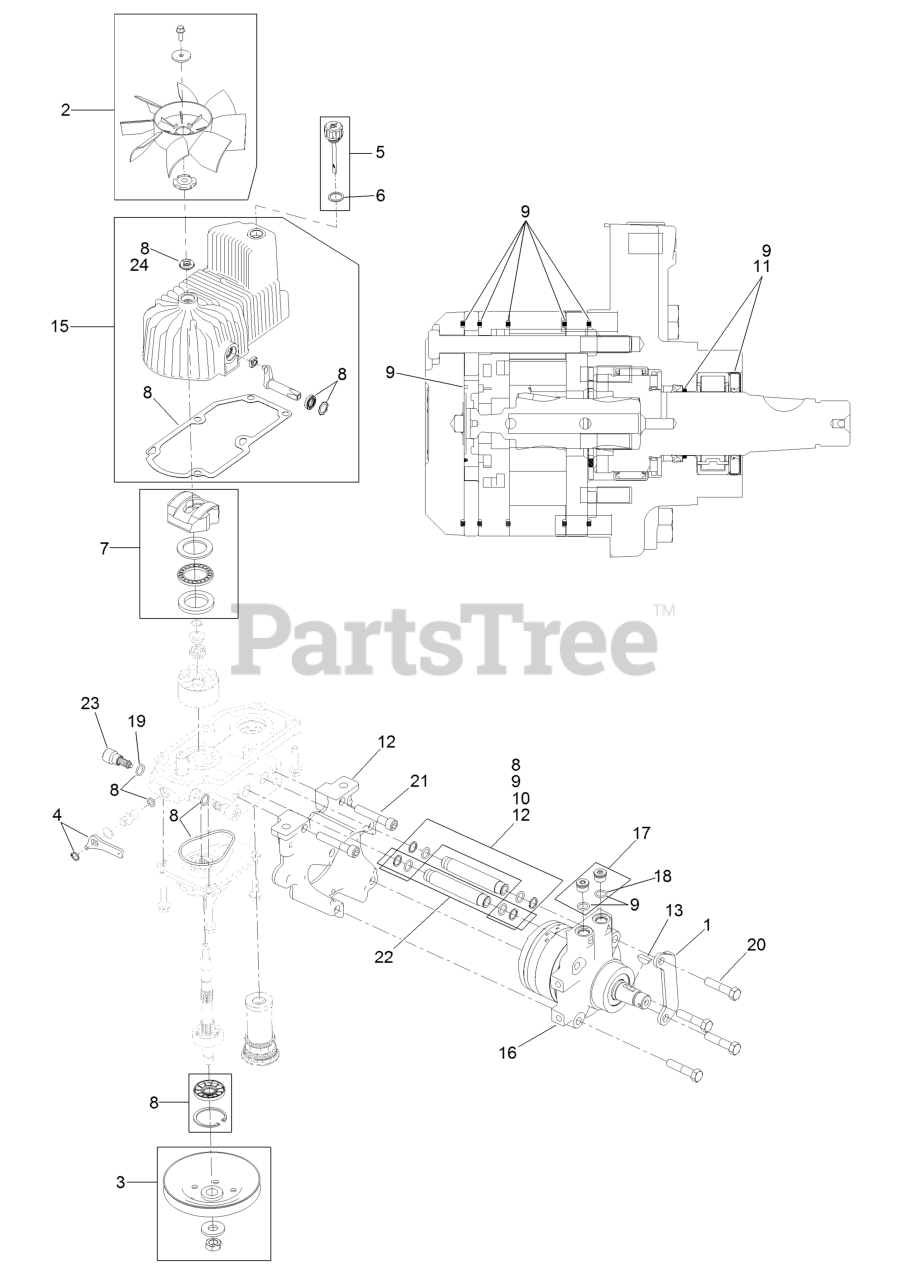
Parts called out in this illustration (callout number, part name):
1	Mount-Shoe, Horse
2	Fan Kit
3	Pulley Kit
4	Handle-Bypass Valve,Hydro
5	Dipstick-Hydro W/Gasket
6	Gasket-Dipstick, Hydro
7	Swash Block Kit
8	Pump Seal Kit
9	Motor Seal Kit
10	Tube Seal Kit
11	Output Shaft Seal Kit
12	Nose Cup-Uht
13	Key-Woodruff
15	Housing-RH
16	Motor-Hydraulic, RH 280Cc
17	Magnetic Plugs Service Kit
19	O-Ring-Check Valve
20	Screw HH
21	Screw-HSH
22	Hydraulic Tube Kit
23	Shock Valve, 16Cc Hydro
24	Seal-Fan Drive
99	Flow Test Kit
99	Puller-Pulley
